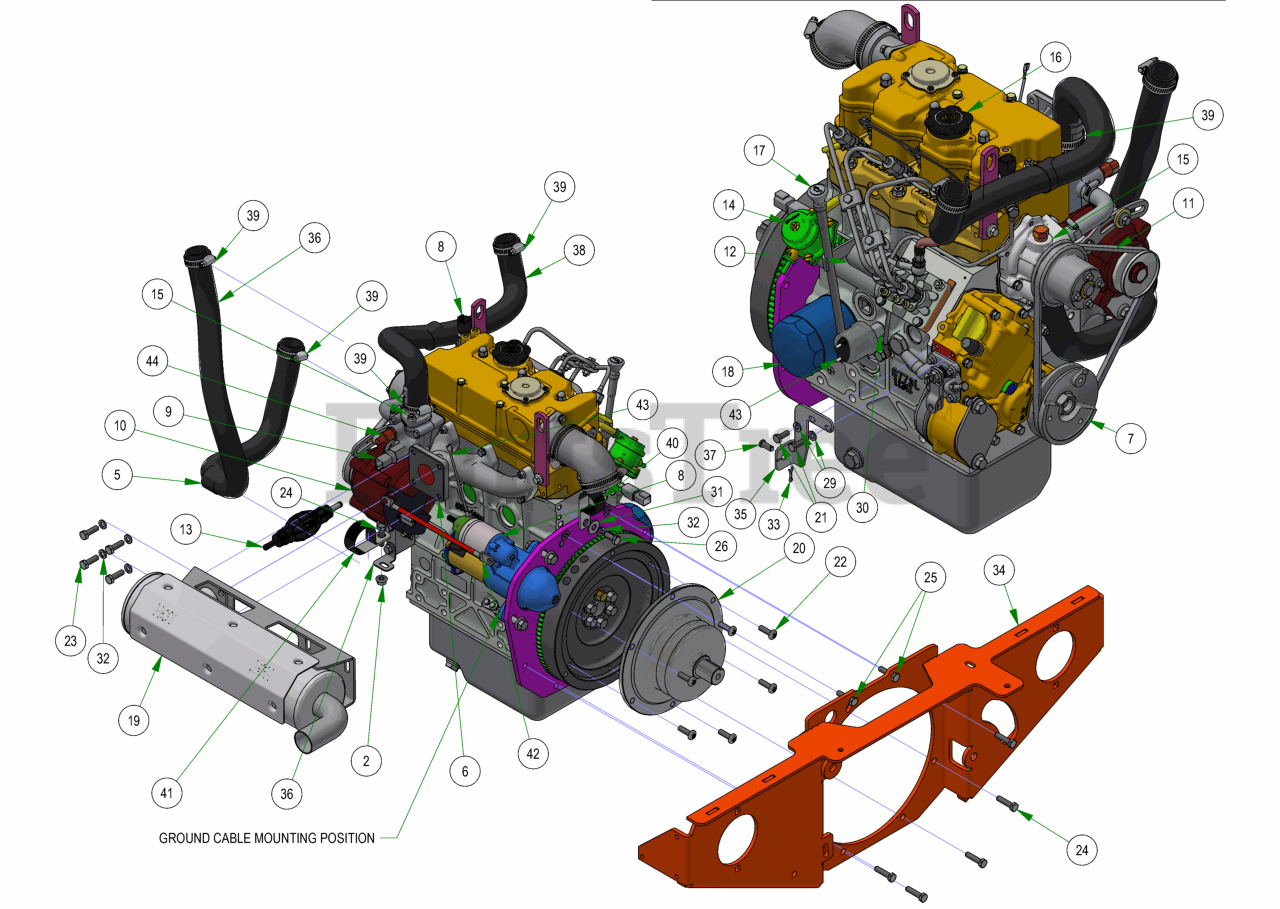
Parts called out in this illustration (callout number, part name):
1	3/8-16 NYLON INSERT FLANGE LOCKNUT (GR.F) ZINC
2	5/16-18 NYLON INSERT FLANGE LOCKNUT ZINC
3	1/2-13 NYLON INSERT FLANGE LOCKNUT ZINC
4	5/16-18 HEX SERRATED FLANGE NUT HARD/ZINC
5	2019 Plastic Mesh Hose Loom
6	Diesel Muffler Gasket
7	24.7HP Perkins Engine, 403J-11
8	OIL PRESSURE SWITCH
9	COOLANT TEMPERATURE SWITCH
10	ALTERNATOR
11	ALTERNATOR BELT
12	FUEL SHUTOFF SOLENOID
13	FUEL PRIMING BULB PUMP
14	FUEL LIFT PUMP
15	WATER PUMP WITH GASKET
16	OIL FILLER CAP
17	OIL LEVEL DIPSTICK
18	OIL FILTER
19	2019 Renegade 1100cc Diesel Muffler
20	2019 Diesel Stub Shaft Double V
21	7/16-20x3” Hex Bolt GR 8 W/ Patch
22	5/16-18 X 1 BUTTON TORX CAP SCREW ZINC
23	M8-1.25 X 25MM DIN 933 HEX TAP BOLT (CL 10.9) ZINC
24	5/16-18 X 1-1/4 HEX C/S (GR.5) ZC
25	M8-1.25 X 30MM DIN 933 HEX TAP BOLT (CL 10.9) ZINC
26	M8-1.25 X 20MM DIN 933 HEX TAP BOLT (CL 8.8) ZINC
27	M12-1.25 X 25MM DIN 961 HEX TAP BOLT (CL 8.8) ZINC
28	3/8-16 X 1 GR 5 Hex Bolts Zinc
29	1/4 SPLIT LOCKWASHER ZINC
30	1/2 SPLIT LOCKWASHER (GR.8) ZINC/YELLOW
31	5/16 USS FLAT WASHER (7/8 OD) ZINC
32	5/16 SPLIT LOCKWASHER ZINC
33	3/32 X 1/2 COTTER PIN ZINC
34	2020 Diesel Pump Plate Weldment - Painted
35	Throttle Bracket
36	Diesel Radiator Hose Clamp Bracket
37	1/4 X 5/8 CLEVIS PIN PLAIN
38	2019 Diesel Radiator Hose Upper
39	1 1/8" Hose Clamp
40	Diesel Hydraulic Hose Clamp
41	Diesel Clamp 1 3/4" Vinyl
42	Red Battery Cable Alternator to Starter Cable
43	2022 DIESEL JUMPER WIRE, WHITE, 14AWG
44	Coolant Temperature Sender
